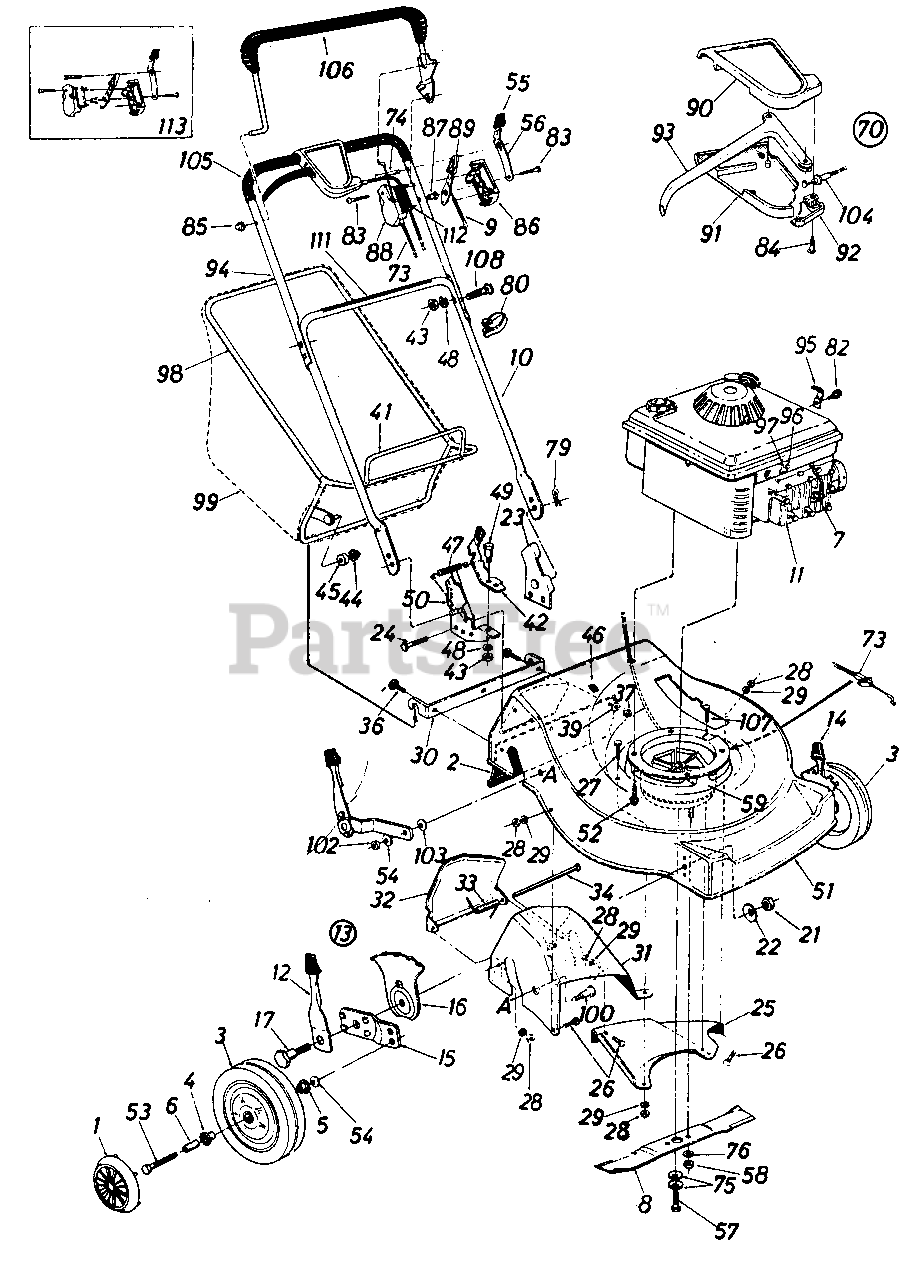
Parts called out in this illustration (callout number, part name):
1	Hub Cap-Plastic
2	Rear Flap Ass'y.
3	Front Wheel Ass'y. Comp.
4	Beari ng
5	Bearing
6	Spacer
7	Spark Plug Boot
8	22" Blade
9	Throttle Control Wire-58"
10	Lower Handle (Chrome)
11	Engine
12	Spring Lever Ass'y. wlKnob
13	Height Adjust. Ass'y.-R.H.
14	Height Adjust. Ass'y.-L.H.
15	Pivot Bar
16	Index Plate
17	Shld. Bolt .50" Dia. x .375"
21	Hex Nut 3/8-16 Thd.
22	Bell-Wash. .39" I.D. x 1.38" O.D.
23	Handle Brkt. Ass'y.-L.H.
24	Hex Wash. Hd. AB-Tap Scr. 1/4 x .62" Lg.
25	Rear Baffle-L.H.
26	Carriage Bolt 1/4-20 x .50"
27	Hex Bolt 1/4-20 x .88" Lg.
28	Hex Nut 1/4-20 Thd.
29	L-Wash. 1/4" I.D.
30	Grass Catcher Hitch Brkt.
31	Rear Chute Baffle Ass'y.
32	Chute Door
33	Torsion Spring
34	Hinge Pin .250" Dia. 7.88" Lg.
36	Carriage Bolt 1/4-20 x .75"
37	Sems Nut 1/4 -20 Thd.
39	Fl-Wash. .285" I.D. x 1.25"
43	Hex Nut 5/16-18 Thd.
44	Push Nut 3/8" Rod
45	Plastic Roller
47	Extension Spring .33" O.D. x 1 l2" Lg
48	L-Wash. 5/16" I.D.
49	Shld. Bolt .437" Dia. x .162"
50	Handle Brkt. Ass'y.-R.H.
51	22" Deck Ass'y.
52	Hex Wash. Hd. TT-Tap Scr. 3/8-16 x 1.0" Lg.
53	Axle Bolt
54	Bell-Wash. 44" I.D. x .88"
55	Spring Lever Knob
56	Lockout Lever
57	Hex Bolt 3/8-24 x 2.00" Lg. (Grade 8)
58	Hex Nut 3/8-24 Thd. (Grade 8)
59	Blade Brake Clutch Ass'y. Comp.
70	Clutch Control Housing-Comp.
73	Clutch Cable-46"
74	Lock Pin .314" Dia. x 1.70"
75	Bell-Wash. .44" I.D. x 88"
76	L-Wash. 3/8" I.D.
79	Intern. Cot. Pin 5/16" Dia.
80	Cable Tie
82	Hex AB-Tap Scr. #8 x .38"
83	Truss Mach. Scr. #12 x 1.50"
84	Flat "C"-Sunk Hd. Scr. #10 x 1.0" Lg.
85	Cap Speed Nut 5/16" Rod
86	Control Panel Half
87	Control Disc Pin
88	Clutch Panel Half
89	Throttle Control Lever
90	Control Cover Half-Upper
91	Control Cover Half-Lower
92	Cable Mtg. Cap
93	Control Lever
94	Upper Handle (Chrome)
95	Casing Clamp
96	Hex Sems Scr. #10-32 x .62" Lg.
97	Casing Clamp
98	Grass Catcher Upper Frame
99	Grass Bag (without Flip Top)
100	Shld. Bolt .500" Dia. x .685"
102	Hex Jam Nut 3/8-16 Thd.
103	Bell-Wash..400" I.D.
104	Clutch Cable-50"
106	Blade Clutch Control Handle
107	Hex Wash. Hd. Self-Tap Scr. 1/4-20 x .75" Lg.
108	Curved Hd. Carr. Bolt 5/16-18 x 1.38
111	Instruction Label-Handle
112	Control Label-Throttle
113	Control Housing Comp.
